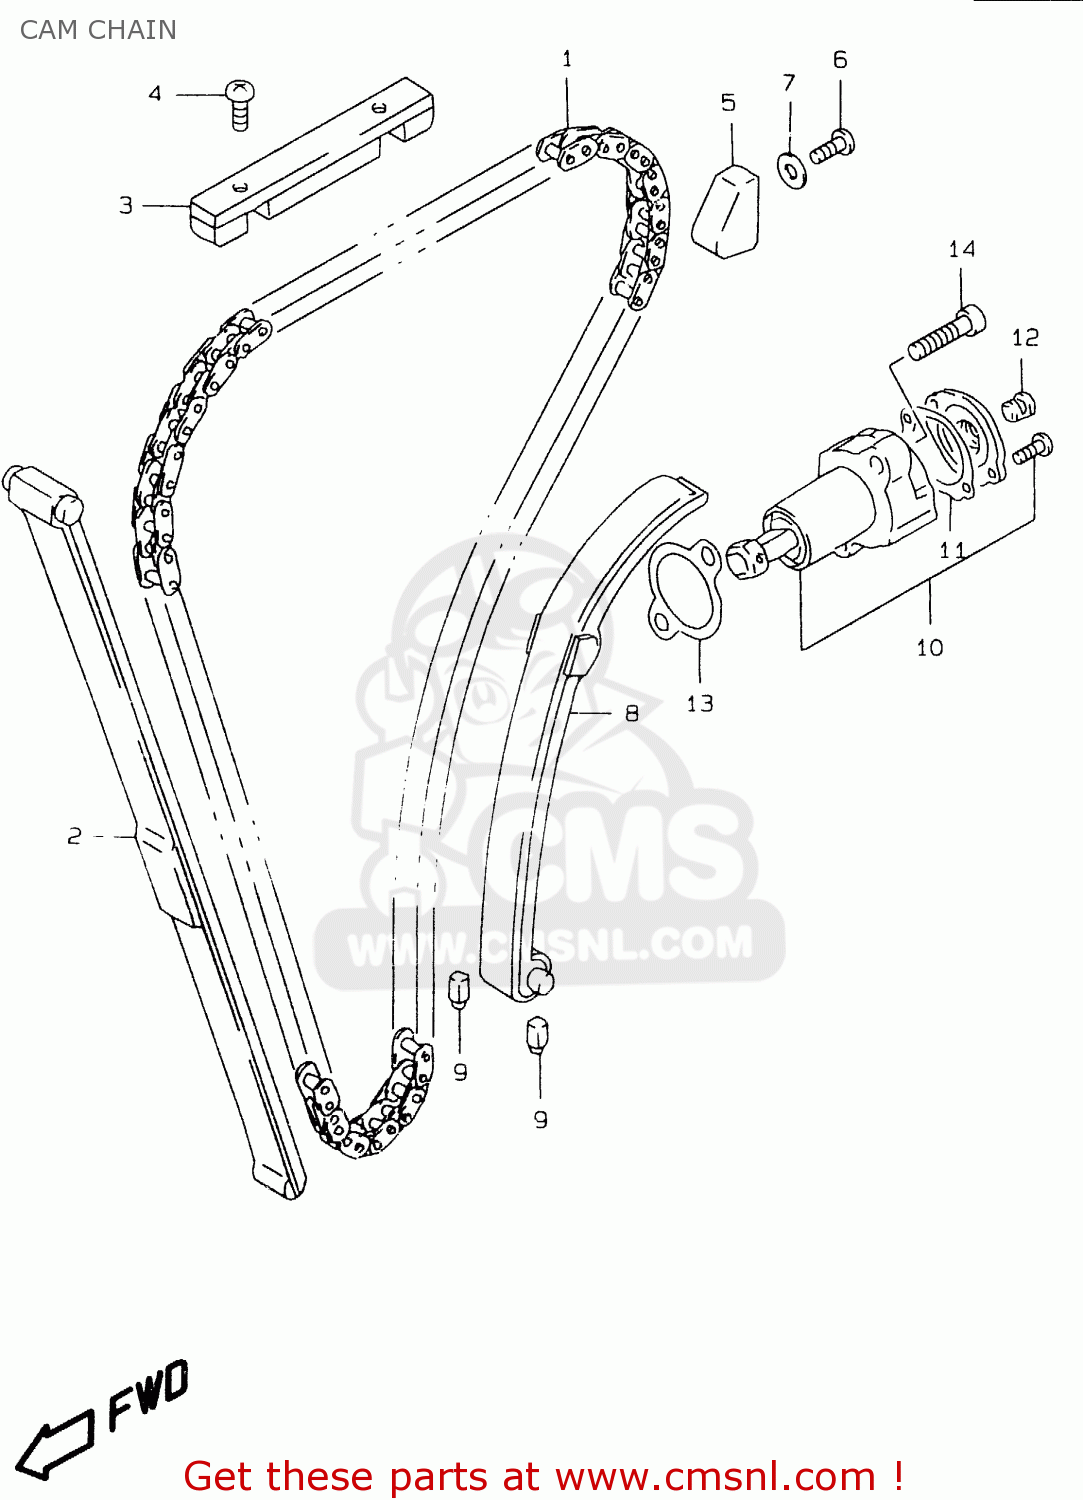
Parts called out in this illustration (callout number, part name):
1	CHAIN,CAMSHAFT DRIVE(120L)
2	GUIDE,CAM CHAIN NO.1
3	GUIDE,CAM CHAIN
4	SCREW
5	GUIDE,CAM CHAIN
6	BOLT
7	GASKET(5.8X13X1.2) (NAS)
8	TENSIONER,CAM CHAIN
9	CUSHION,CAM CHAIN TENSIONER
10	ADJUSTER ASSY,TENSIONER
11	GASKET,ADJUSTER CAP (NAS)
12	PLUG,ADJUSTER
13	GASKET,TENSIONER ADJUSTER (NAS)
14	BOLT,CL.COVER
